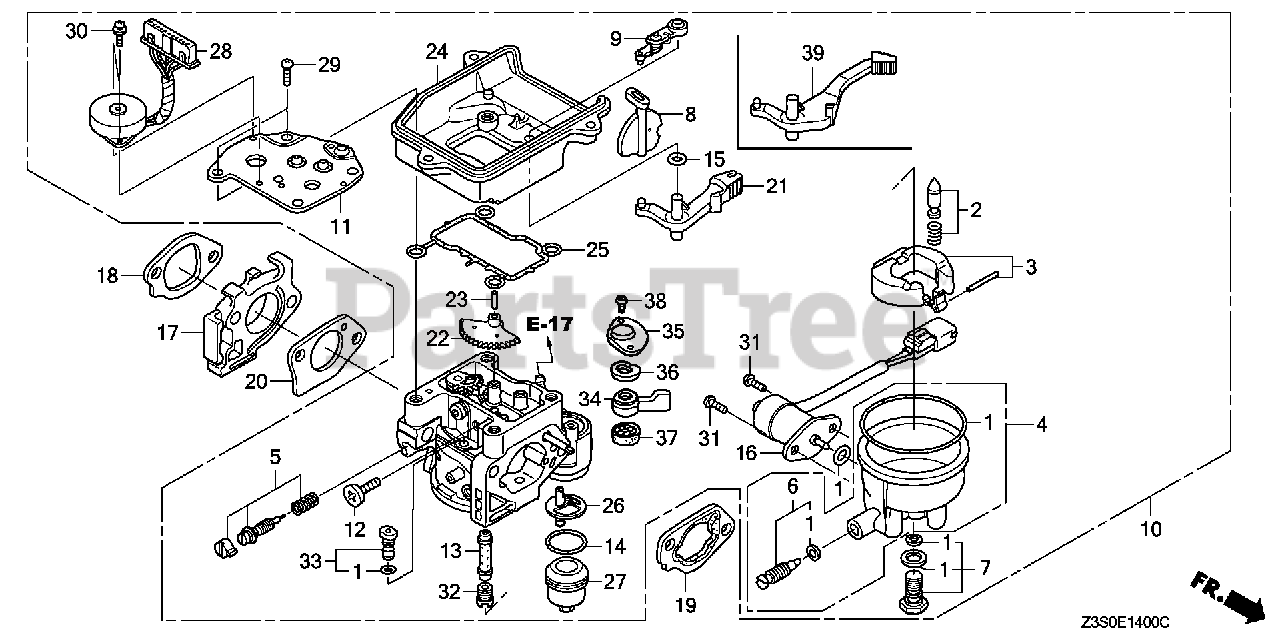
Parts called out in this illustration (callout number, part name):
1	GASKET SET
2	VALVE SET, FLOAT
3	FLOAT SET
4	CHAMBER SET, FLOAT
5	SCREW SET
6	SCREW SET, DRAIN (ADVENTURE GREEN) (CARBURETOR NO.)
7	SCREW SET
8	CHOKE SET (CARBURETOR NO.)
9	ARM, CHOKE (CARBURETOR NO.)
10	CARBURETOR ASSY. (BE87Y E)
11	PLATE, MOTOR (CARBURETOR NO.)
12	SCREW, THROTTLE STOP
13	NOZZLE, MAIN
14	GASKET, FUEL STRAINER CUP
15	O-RING (CARBURETOR NO.)
16	VALVE ASSY., SOLENOID
17	INSULATOR, CARBURETOR
18	GASKET, INSULATOR
19	SPACER, CARBURETOR
20	GASKET, CARBURETOR
21	LEVER, CHOKE
22	GEAR, MIDDLE
23	SHAFT, GEAR CENTER
24	CASE, MOTOR
25	GASKET, MOTOR CASE
26	FILTER, CUP
27	CUP, FUEL STRAINER
28	MOTOR, THROTTLE CONTROL
29	SCREW, PAN (5X20)
30	SCREW-WASHER (3X6)
31	SCREW-WASHER (5X12)
32	JET, MAIN (#108) (CARBURETOR NO.)
32	JET, MAIN (#110) (CARBURETOR NO.)
32	JET, MAIN (#112)
33	JET SET, PILOT (#45) (CARBURETOR NO.)
